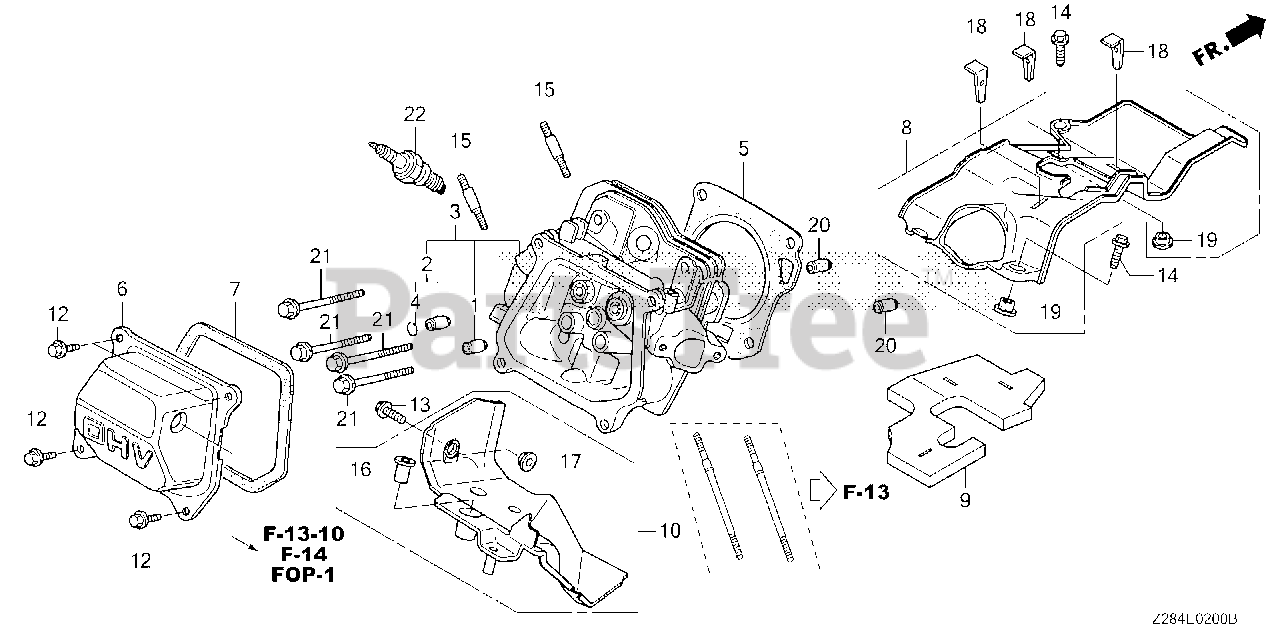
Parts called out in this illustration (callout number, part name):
1	GUIDE, VALVE (OVER SIZE)
2	GUIDE, EX. VALVE (OVER SIZE)
3	CYLINDER HEAD
4	CLIP, VALVE GUIDE
5	GASKET, CYLINDER HEAD
6	COVER, HEAD
7	GASKET, HEAD COVER
8	SHROUD (UPPER)
9	INSULATOR, SHROUD (UPPER)
10	SHROUD (LOWER)
12	BOLT, FLANGE (6X12) (CT200)
13	BOLT, FLANGE (6X14) (CT200)
14	BOLT, FLANGE (6X20) (CT200)
15	BOLT, STUD (8X32)
16	COLLAR A, SHROUD (LOWER)
17	COLLAR B, SHROUD (LOWER)
18	CLIP, INSULATOR BIND (A)
19	COLLAR, RECOIL STARTER
20	PIN, DOWEL (10X16)
21	BOLT, FLANGE (8X60)
22	SPARK PLUG (BPR5ES) (NGK)
22	SPARK PLUG (W16EPR-U) (DENSO)
22	SPARK PLUG (BPR6ES) (NGK)
22	SPARK PLUG (W20EPR-U) (DENSO)
